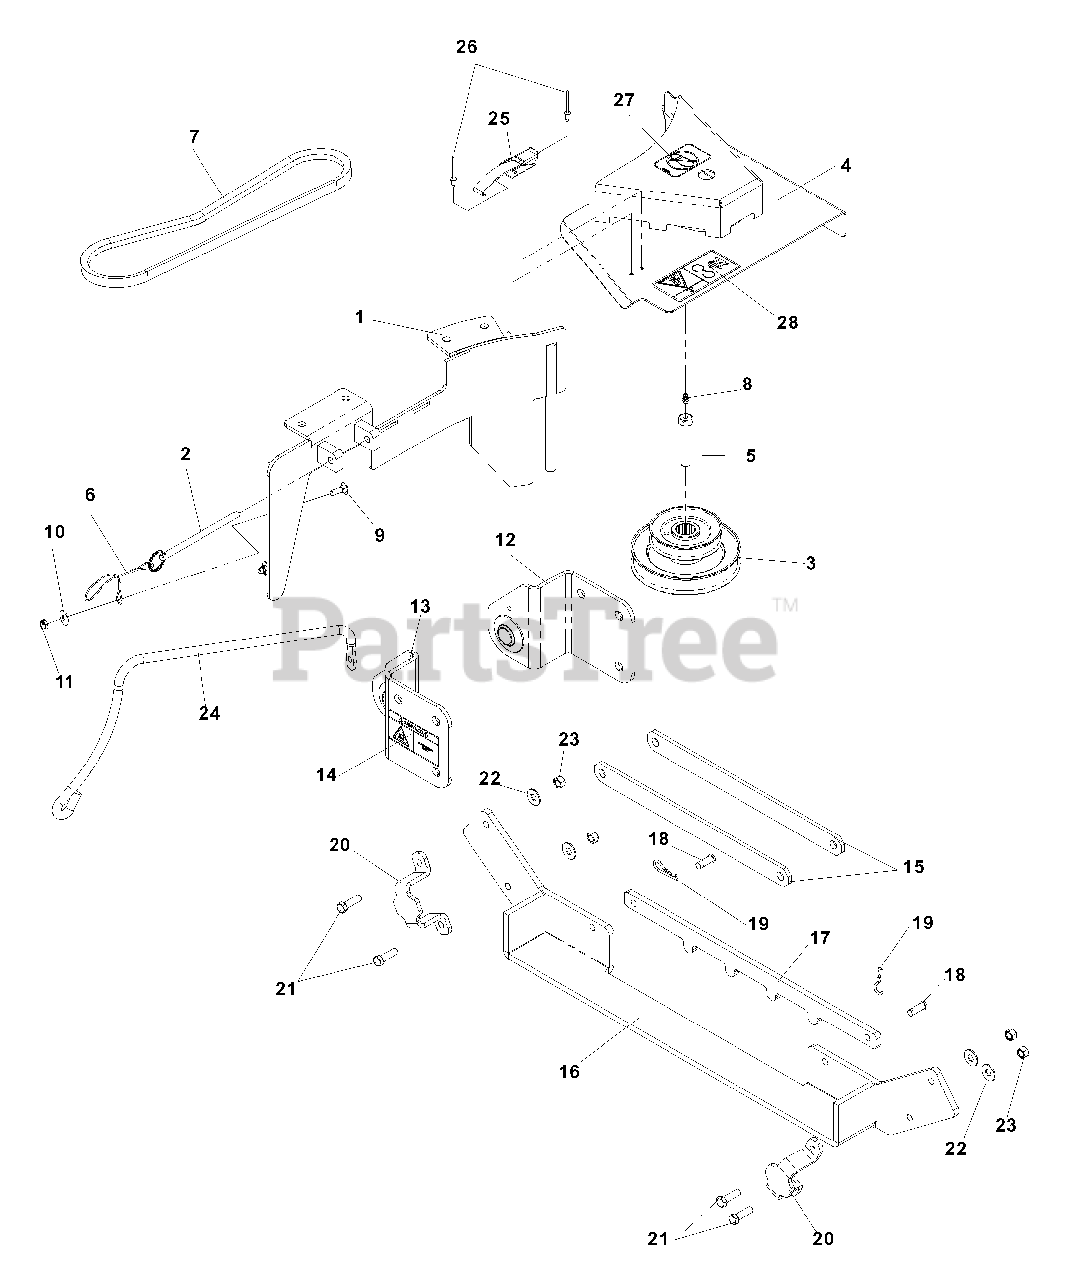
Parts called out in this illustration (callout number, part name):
1	BLOWER DECK PLATE, 61"
3	STACK PULLEY, 61" DECK
4	BELT SHIELD, 61" DECK
5	HCS, 7/16-20 x 2 1/2, GR8
7	BELT, 52" DECK
7	BELT, 61" DECK
8	ZERK
9	RHSNB, 1/4-20 x 3/4, GR2
10	WASHER, 1/4
11	NUT, 1/4-20, JAM, NYLOC
12	HITCH BRACKET, LT
13	HITCH BRACKET, RT
14	DECAL, HOT SURFACE
16	WEIGHT BAR
17	HOLD DOWN, WEIGHT BAR
18	CLEVIS PIN
19	SPRING RETAINER
20	WEIGHT KEEPER
21	HCS, 3/8-16 x 1 1/4,
22	WASHER, 3/8
23	NUT, 3/8-16, NYLOC
24	HOSE SUPPORT
25	DRAW LATCH
26	RIVET, BLIND, 5/32 DIA.
27	DECAL, NO STEP
28	DECAL, BELT DRIVES
